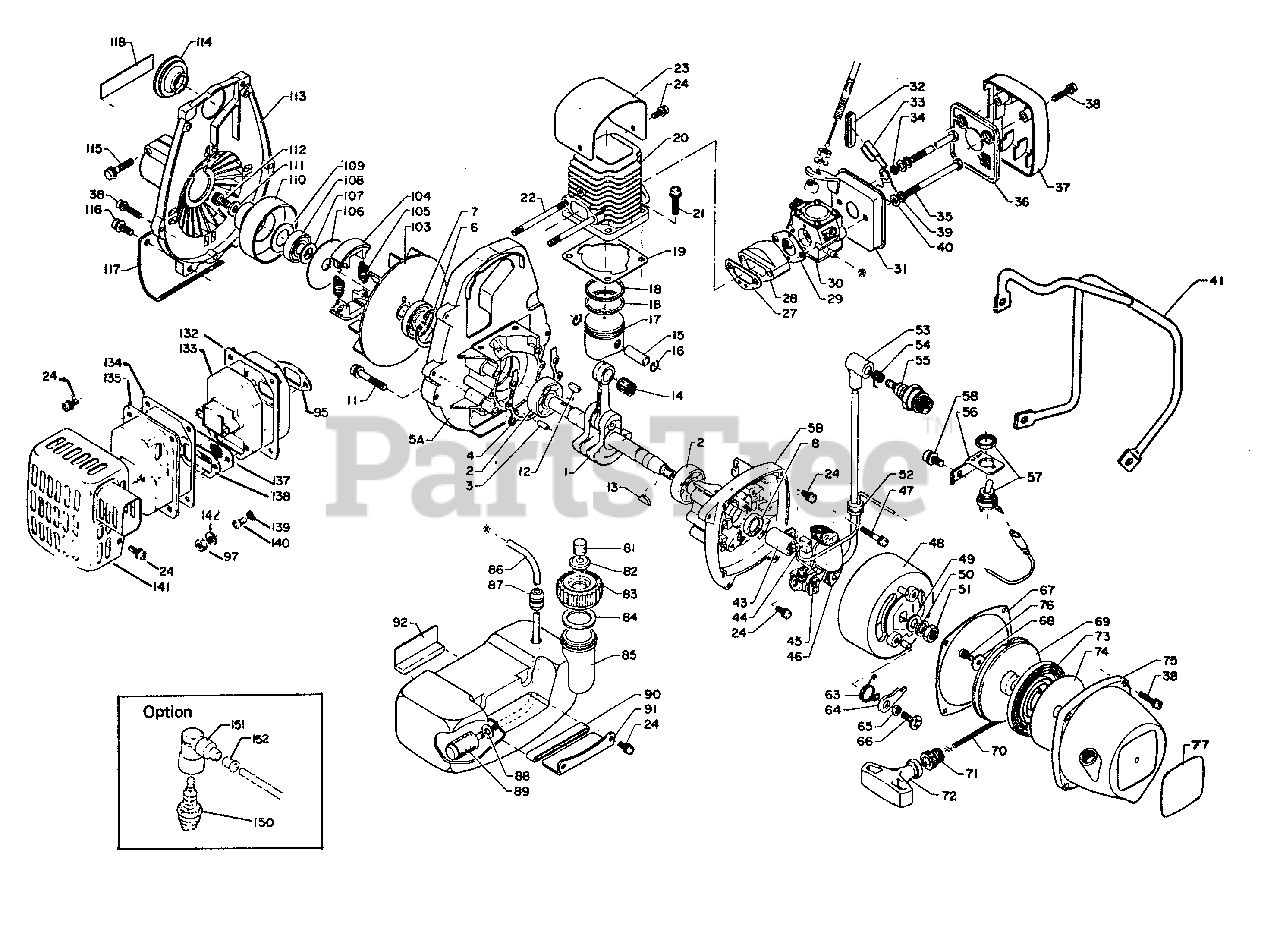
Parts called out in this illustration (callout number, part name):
1	Crankshaft Ass'y
2	Ball Bearing 6201
3	Knock Pin
4	Gasket, Crankcase
5	Crankcase Set
6	Circlip 32
7	Oil Seal
8	Oil Seal
11	Screw 5 x 30
12	Woodruff Key
13	Woodruff Key
14	Needle Bearing
15	Piston Pin
16	Circlip, Piston Pin
17	Piston
18	Piston Ring
19	Gasket, Cylinder Base
20	Cylinder
21	Screw 5 x 20
22	Stud
23	Cylinder Cover
24	Screw 4 x 10
27	Gasket
28	Insulator
29	Gasket
30	Carburetor Ass'y
31	Case, Air Cleaner
33	Choke Shutter
34	Spacer
36	Air Filter
37	Cover, Air Cleaner
38	Screw 4 x 20
39	Spring Washer
40	Washer 5
43	Condenser
45	Breaker Point Set
46	Ignition Coil
47	Screw 4 x 25
48	Flywheel
50	Spring Washer
53	Cap, Spark Plug
54	Coil Spring, Plug Cap
55	Spark Plug
56	Bracket, Switch
57	Switch
58	Screw 5 x 14
63	Spring, Ratchet
64	Ratchet
65	Spacer, Ratchet
66	Screw
67	Gasket, Starter Case
69	Recoil Drum
70	Starter Rope
71	Rope Guide
72	Starter Handle
73	Rewind Spring
74	Side Plate
75	Starter Case
76	Screw 4 x 10
82	Check Valve
83	Case Ass'y, Fuel Tank
84	Gasket, Fuel Tank Cap
85	Fuel Tank
86	Fuel Pipe
88	Washer 6
89	Fuel Stainer
90	Cushion
91	Bracket, Fuel Tank
92	Bracket, Fuel Tank
95	Gasket, Muffler
97	Lock Nut 5
103	Fan
104	Clutch Shoe
105	Clutch Spring
106	Side Plate, Clutch
108	Ball Bearing 6000
110	Clutch Drum
112	h.s.h. Bolt 6 x 10
113	Fan Cover
114	Boot, Plug Cap
115	Bolt 5 x 25
116	Screw 5 x 14
117	Bracket
118	Decal, Model
132	Muffler A
133	Muffler B
134	Gasket
135	Muffler C
139	Washer, Lock 4
140	Screw 4 x 8
141	Cover, Muffler
142	Washer 5
150	Spark Plug BMR 6A
151	Cap, Spark Plug
152	Adapter, Cap
